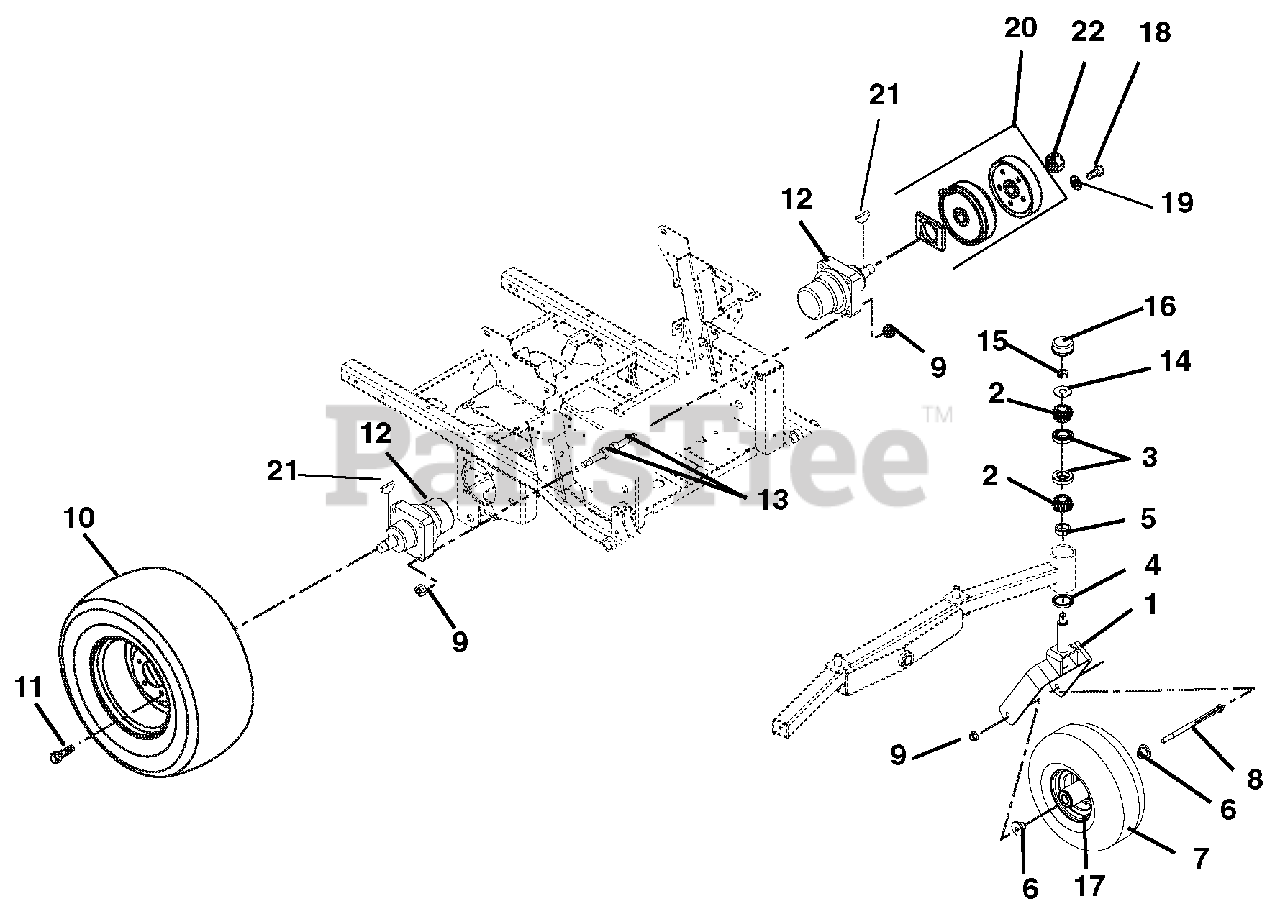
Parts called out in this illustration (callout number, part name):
1	WMT - FRONT FORK
2	BRG-CONE 1.25X.66
3	BRG-CUP 2.328X.465
4	SEAL, OIL 1.75 X 2.332 X .312
5	SPCR, 1.258ID X 1.750OD X.550
6	SPACER, FRONT WHEEL
7	TIRE/WHEEL ASSY, 15X6.00-6
8	@BLT-HEX .50-13X9.00 GR5 YWZC
9	@NUT-LK-TOP-FLG .50-13 YWZC
10	TIRE/WHEEL ASSY, 24X11.50-12
11	BLT-LUG .50-20X1.38 YWZC
12	WHEEL MOTOR, 18E (CCW)
13	BLT-HEX .50-13X2.75 YZ GR8
14	@WSHR-FL-STL.812X2.00X.148YWZC
15	NUT-JAM CTRLK .75-16 YWZC
16	CAP, DUST
17	BRG, 25MM ID X 52MM OD X 15MM
18	BLT-HEX .31-18X1.50 GR8YZ EP30
19	@WSHR-LK .31X.078 REG YWZC
20	KIT, BRAKE SERVICE (1-SIDE)
21	KEY-WDRF .31X1.00 SFT #B
22	NUT-LK-JAM-PTCH 1.00-20
